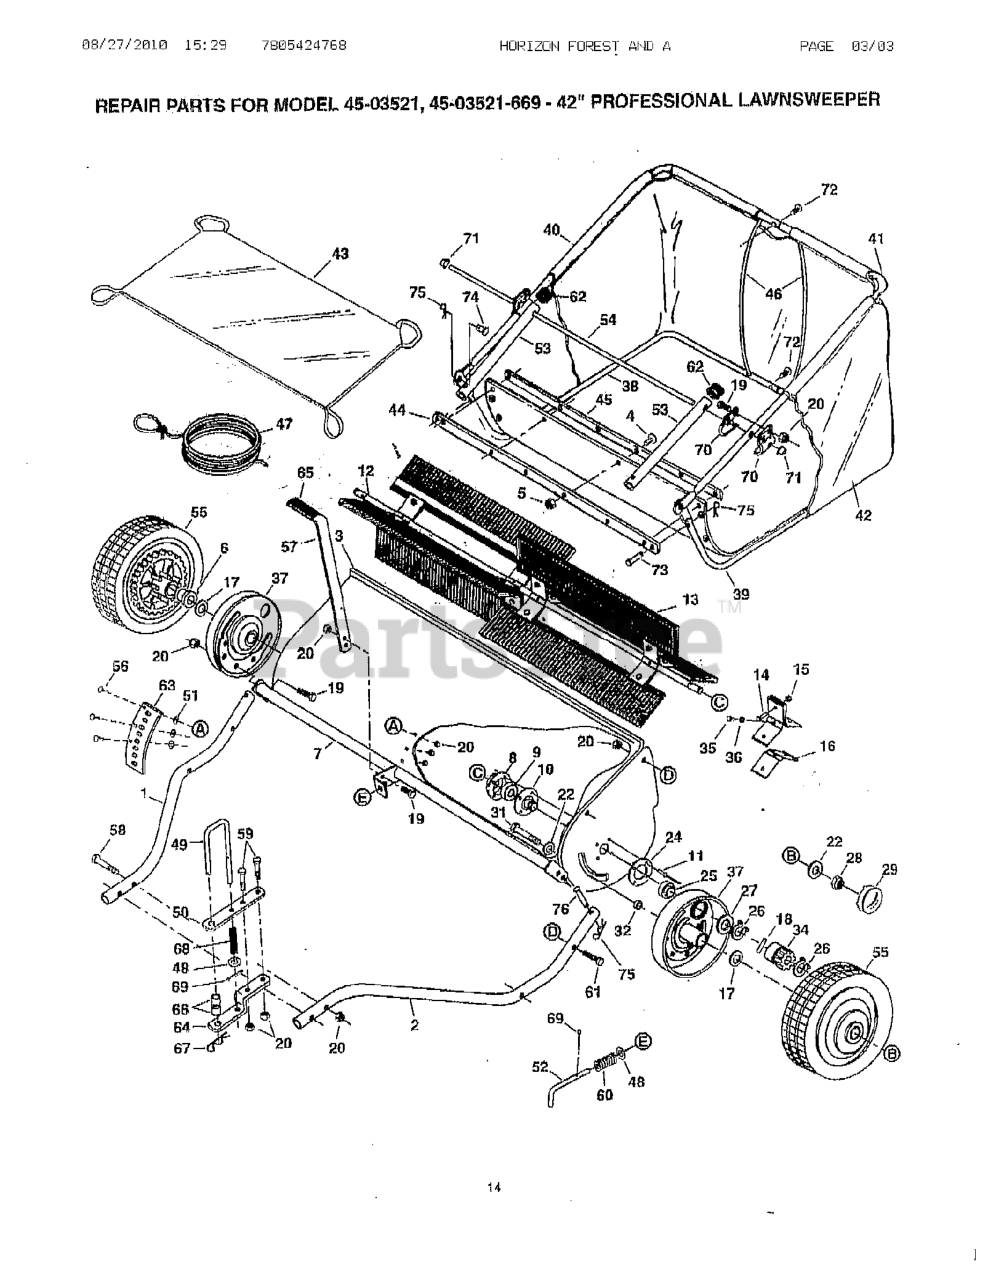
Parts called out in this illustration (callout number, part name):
1	Hitch Tube, R.H.
2	Hitch Tube, L.H.
4	Truss Hd. Slotted Scr. #10-32 x 5/8" Lg.
5	Nylock Nut, #10-32
6	Wheel Bearing
8	Retainer, Dust Cover
9	BEARING. BALL
10	Brush Bushing Ass'y.
12	Brush Shaft
13	Brush, 42"
14	Hex Bolt 1/4-20 x 1.0" Lg.
15	Hex Nut, Nylock 1/4-20 Thread
16	Brush Retainer
17	WASHER, FLAT 3/4ID X 1-1/8 00 X .030 THK
18	Dowel Pin (Drive)
19	Bolt, Hex 5/16-18 x 3/4" Lg.
20	Hex Nut, Nylock 5/16-18 Thread
21	Spacer, .41" x 1.125" x .50"
22	Washer, Flat 1-1/2" x .375" x .062"
23	Washer, Flat .596 x .859 x .025
24	Washer, Special
25	Spacer, .78" x 1.25" x .50"
26	Retaining Ring - .594" I.D.
27	Fl.-Washer (Shim) .596 x 1.125 x .025
28	Nut, Hex Lock 3/8-24 Thread
30	Washer, Hub Cap
31	Bolt, Hex 3/8-24 x 3-1/4" Lg.
32	Spacer 13/32 x 5/8 x 3/16
34	Gear, Pinion L.H.
35	Hex Bolt 1/4" x 5/8" Lg.
36	WASHER, 1/4" SPRING LOCK
37	Dust Cover Assembly
38	Tube, Lower Hopper Frame R.H.
39	Tube, Lower Hopper Frame L.H.
40	Tube, Upper Hopper Frame R.H.
41	Tube, Upper Hopper Frame L.H.
42	Hopper Bag
43	Wind Screen
44	Strap, Bag Frame
45	Retainer, Bag
46	Hopper Support Rod 34" Lg.
47	Hopper Rope
48	Washer, 3/8" Std. Wrt.
50	Bracket, Hitch (Straight)
51	Spacer, 3/8" I.D. x 5/8" O.D. x 1/4"
53	Tube, Bag Arm
54	Rod, Hopper Bag Pivot
56	Carriage Bolt, 5/16" x 1" (Grade 5)
58	Bolt, Hex 5/16-18 x 3" Lg.
59	Bolt, Hex 5/16-18 x 2-1/4" Lg.
61	Hex Bolt, 5/16-18 x 1-3/4" (Grade 5)
62	Cap, Vinyl
64	Bracket, Hitch
65	Grip, Height Adjust
66	Hitch Adjustment Tubes
67	Hairpin Cotter, 3/32" x 2-5/16"
68	Spring, Hitch Pin
69	Pin, Cotter 1/8" x 3/4" Lg
70	Hopper Mounting Clamps
71	Palnut, 3/8"
72	Plug, 1/4"
74	Pin, Clevis 3/8" x 1/2" (Special)
75	Hairpin Cotter, 3/32" x 1.8"
76	Pin, Clevis 1/4" x 1-1/2" Lg.
